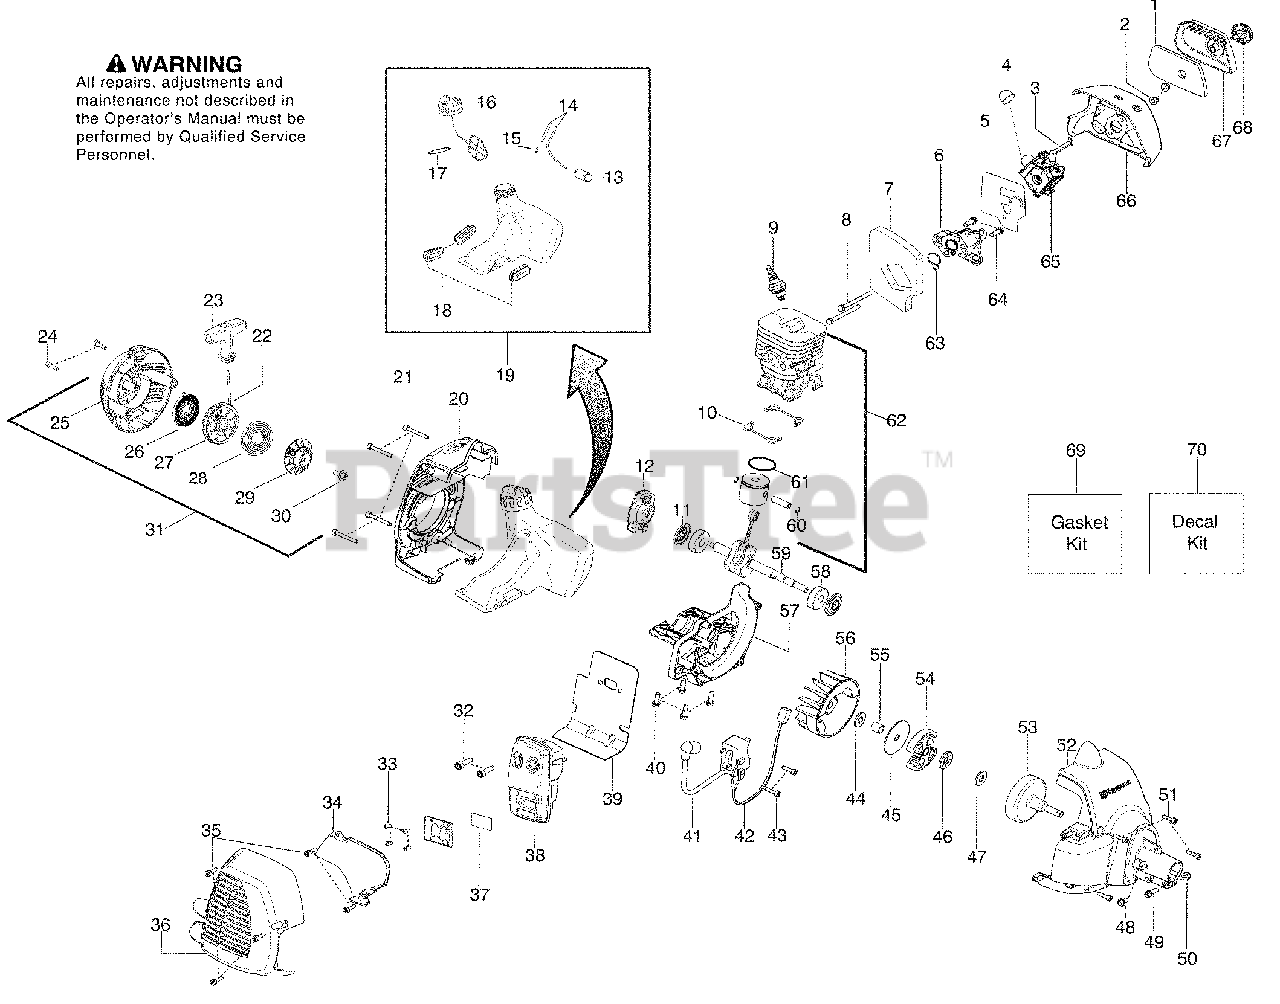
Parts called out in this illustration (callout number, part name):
2	Nut - Carb. Screw
3	Lever - Choke
4	Bulb - Purge
5	Kit - Carb. Gasket
6	Adaptor - Carb.
7	Foam - Gasket (kit)
9	Plug - Spark (RCJ-8Y)
10	Seal - Cylinder (kit)
11	Seal - Crankshaft (kit)
12	Assy - Starter Pawl
13	Assy - Fuel Filter
14	Kit - Fuel Line
15	Fitting - Fuel line
16	Assy - Cap w/ret.
17	O-ring - Fuel Cap (kit)
18	Isolator - Fuel Tank
19	Kit - Fuel Tank Assy.
20	Shroud - Rear
22	Kit - Rope
23	Handle - Starter
24	Screw
25	Hsg. - Starter w/eyelet
26	Kit - Spring
27	Kit - Starter Pulley
28	Spring - Driver
29	Pulley-Driver
31	Assy - Starter Hsg.
32	Bolt - Muffler
33	Screw
34	Shield - Heat
36	Guard - Muffler
37	Kit - Spark
38	Kit – Muffler
39	Gasket - Paper Met.(kit)
42	Assy - Leadwire
45	Washer - Clutch
46	Bearing - Thrust
47	Washer - Thrust
52	Assy - Fan Housing
53	Assy - Clutch Drum
54	Assy - Clutch Assy
57	Crankcase - Cast
59	Assy - Crankshaft
60	Retainer - Piston Pin
61	Ring - Piston
62	Kit - Piston/Cyl.
63	Seal - adaptor (kit)
65	Kit - Carb.
66	Airbox
67	Cover - Air Box
68	Assy - Knob
69	Kit – Gasket
70	Kit - Decal
